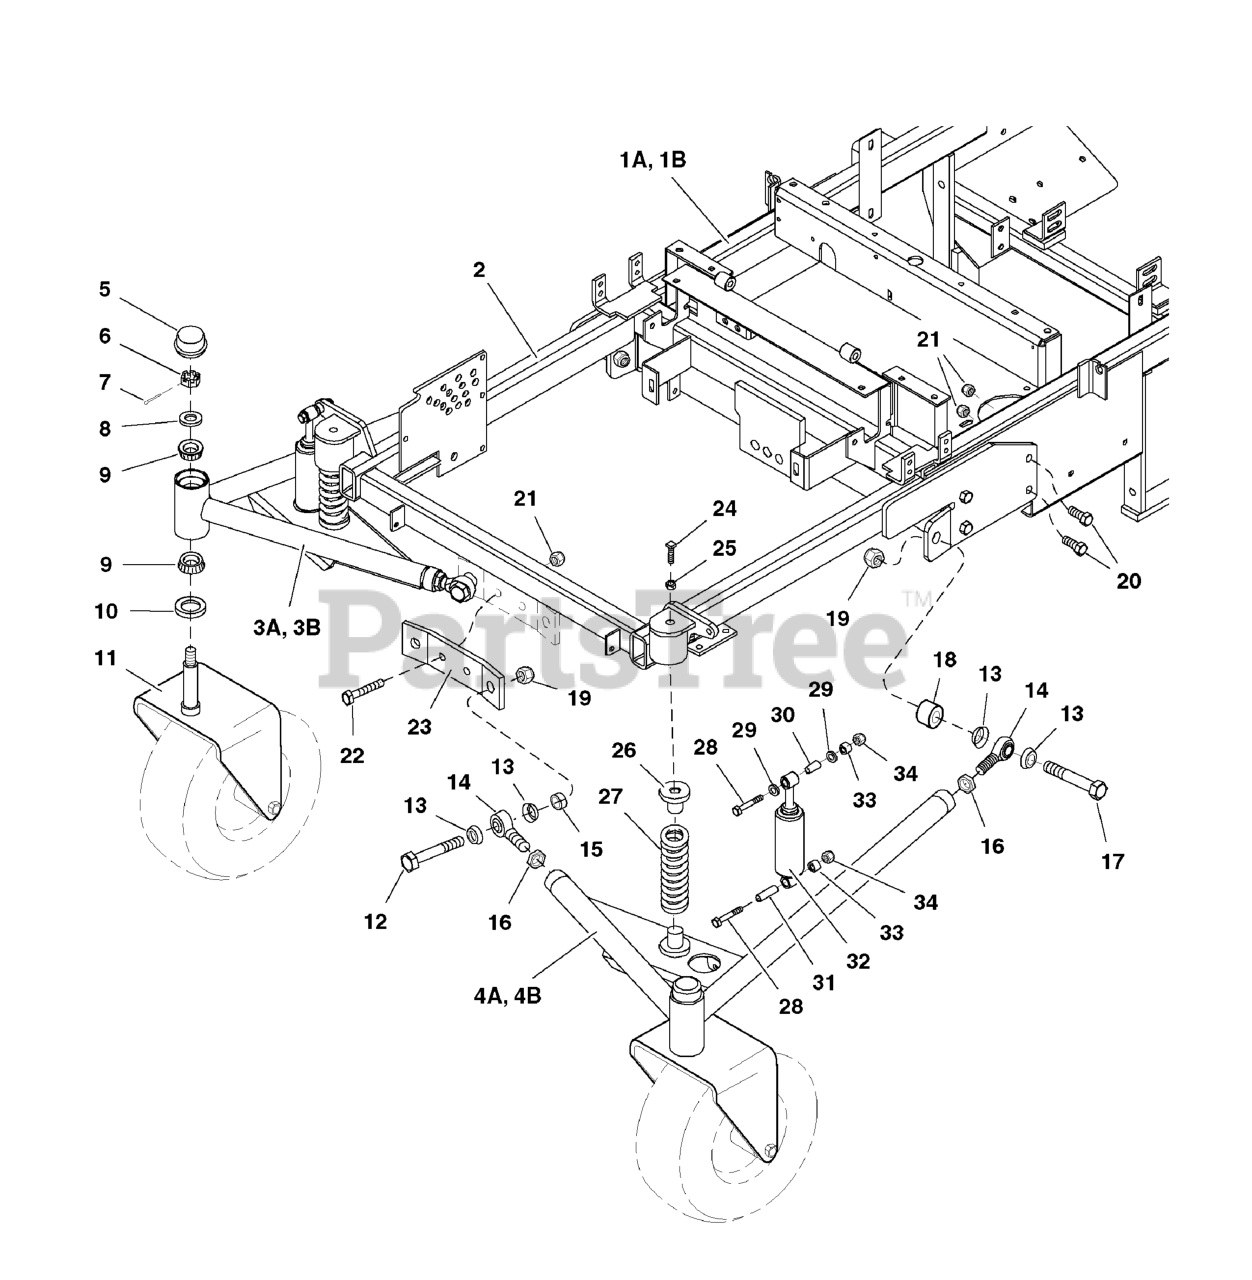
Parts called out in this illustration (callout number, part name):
1A	MAIN FRAME
1B	MAIN FRAME
2	FRONT FRAME
3A	SUSPENSION ARM-RH
3B	SUSPENSION ARM-RH
4A	SUSPENSION ARM-LH
4B	SUSPENSION ARM-LH
5	CAP, DUST
6	NUT, Hex, Slotted, 3/4-16
7	PIN, COTTER, 1/8 X 1-1/4
8	WASHER, 3/4 SAE
9	BEARING, TAPERED ROLLER, 1"
10	SEAL, GREASE
11	CASTER TIRE MOUNT
12	BOLT, 3/4-16 X 3" YZ GD5
13	SEAL, 3/4" ROD END
14	BALL JOINT, 3/4-16, MALE
15	SPACER, .76 X 1.00 X .50, CZ
16	NUT, Hex, Jam, 3/4-16
17	BOLT, 3/4-16 X 4" YZ GD5
18	SPACER, .75 X 1.50 X 1.00, CZ
19	NUT, Hex, Nylon Lock, 3/4-16
20	BOLT, 1/2-13 X 1-1/4 GD5 CZ
21	NUT, Hex, Nylon Lock, 1/2-20
22	BOLT, 1/2-20 X 1-3/4" GD8 CZ
23	PLATE, Suspension Arm Support
24	SET SCREW, Square Head, 1/2-13 x 2-1/2
25	NUT, Hex, Jam, 1/2-13
26	SPRING RETAINER
27	SPRING, SUSPENSION
28	BOLT, 3/8-16 X 2-1/2" GD5 CZ
29	WASHER, 3/8 SAE
30	SPACER, .38 x .50 x 1.00
31	SPACER, .38 x .50 x 1.56
32	SHOCK ABSORBER
33	SPACER, .39 X .75 X .38, PM, CZ
34	NUT, Hex, Side Lock, 3/8-16
